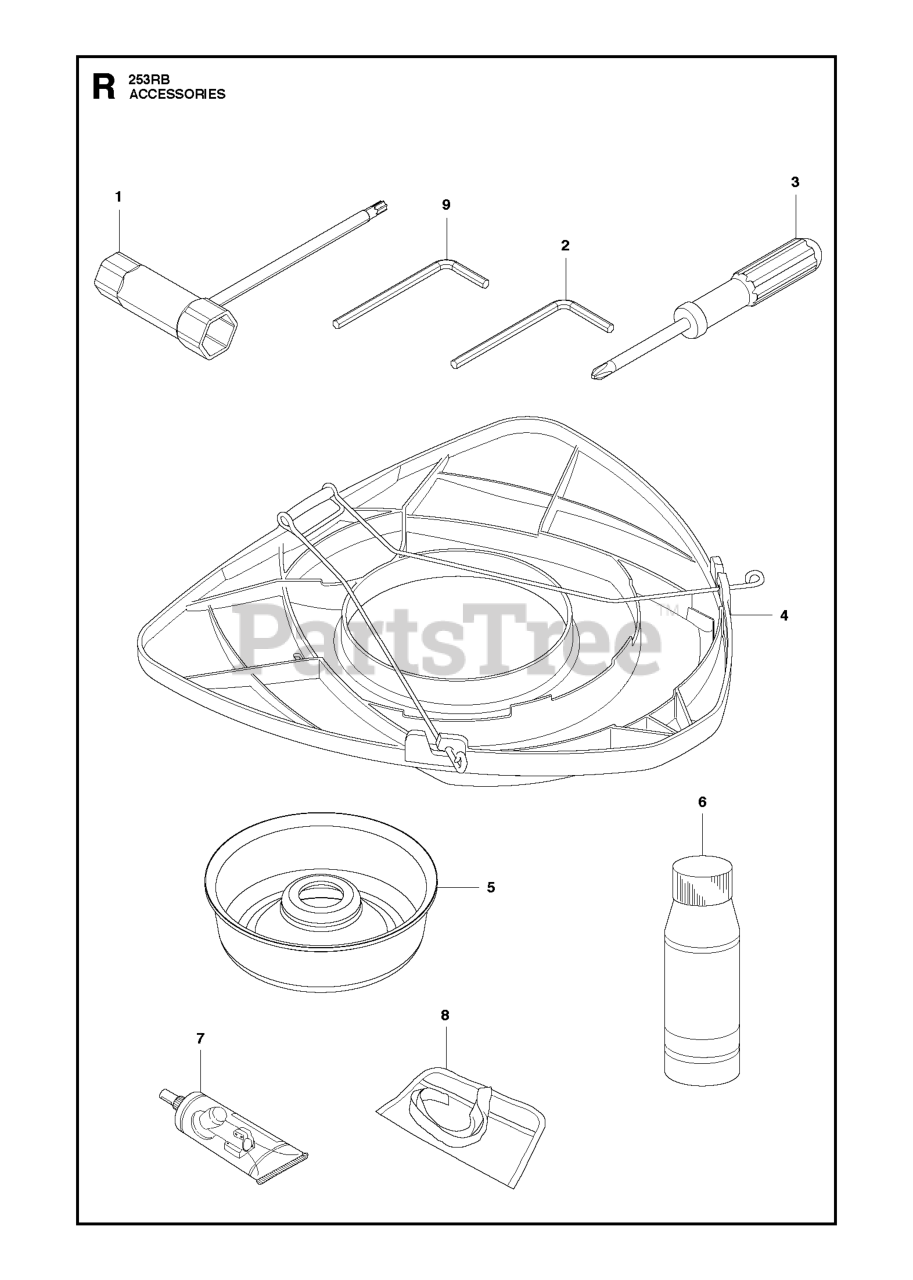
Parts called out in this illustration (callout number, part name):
4	TRANSPORT GUARD
5	SUPPORT CUP
6	Air Filter Oil 1l.
7	BEVEL GEAR GREASE
